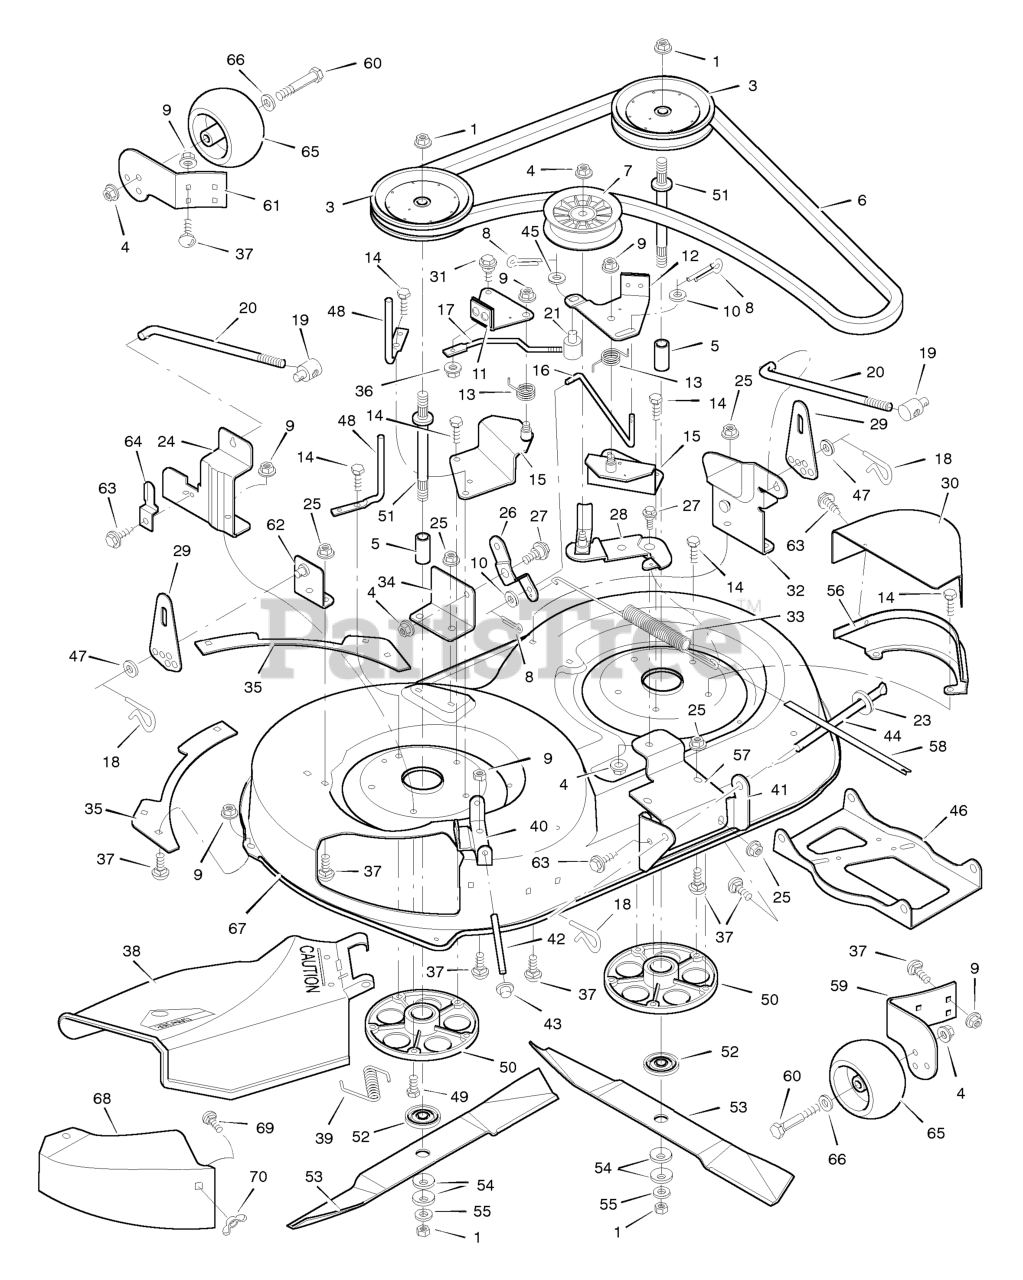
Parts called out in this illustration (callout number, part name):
1	Nut, Hex
3	Pulley, Jackshaft
4	Locknut, Flange
5	Spacer
6	Belt, Blade Drive
7	Pulley, Idler
8	Pin, Cotter
9	Locknut, Flange
11	Brake Assembly, Right
12	Brake Assembly, Left
13	Spring, Torsion
14	Bolt, Hex
15	Bracket Assembly, Brake
16	Rod, Brake
17	Rod, Cross Link
18	Pin, Hair
19	NUT, Adjusting, 1/2-13
20	Rod, Adjuster
21	Nut, Adjustable
24	Bracket, Right
25	Nut, Flange
26	Bracket, Pivot
27	Bolt, Carriage
28	Arm Assembly, Idler
29	Plate, Adjuster
30	Cover, Pulley
31	Bolt, Shoulder
32	Bracket Assembly, Left Lifter
33	Spring, Extension
34	Bracket, Pivot
36	Locknut, Flange
37	Bolt, Carriage
38	Deflector Assembly, Chute
39	Spring, Torsion
40	Bracket, Hinge
41	Bracket, Front Hanger
42	Rod, Deflector
43	Cap, Push On
44	Rod, Hanger
46	Hanger, Front
48	Rod, Belt Guide
49	Bolt, Hex
50	Housing, Jackshaft
51	Jackshaft
52	Adapter, Blade
53	Blade, 42" (Left)
54	Washer, Belleville
55	Washer
56	Bracket, Pulley Cover
57	Bracket, Idler Mount
58	Indicator, Plastic
59	Bracket, Right Wheel
60	BOLT, Gauge Wheel
61	Bracket, Left Wheel
62	Bracket Assembly, Right Lifter
64	Guide, Belt
65	Wheel, Gauge
66	Washer
67	Housing, Blade
68	Cover, Mulcher
69	Bolt, Carriage
70	Wingnut
